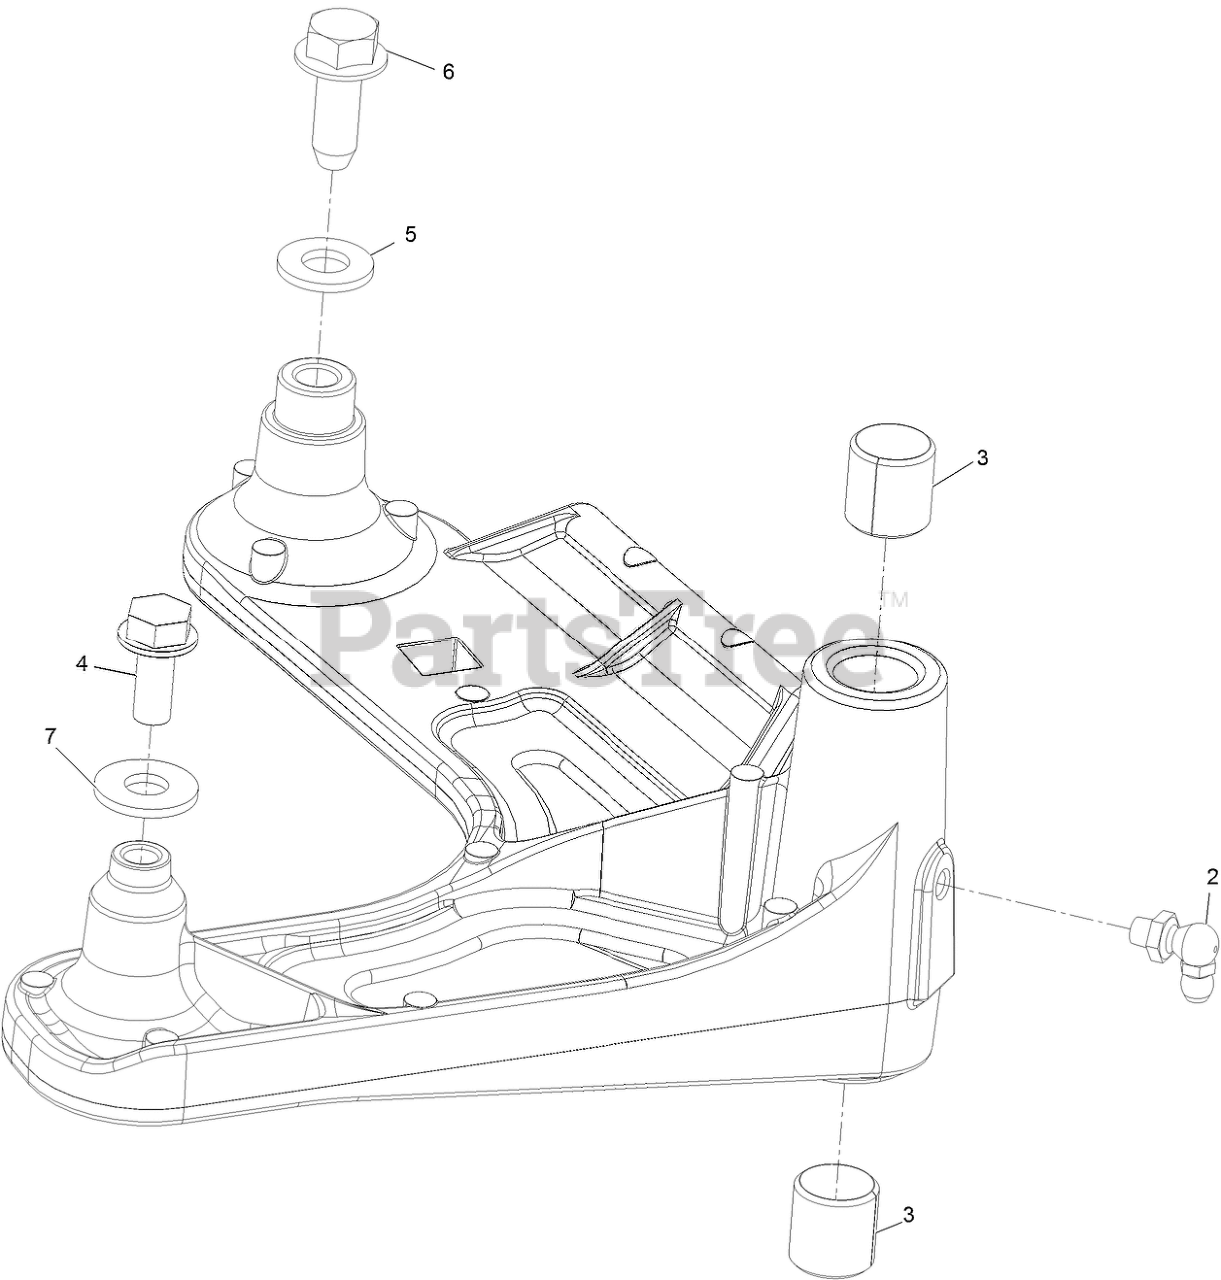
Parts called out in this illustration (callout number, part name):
2	FITTING-GREASE, 90 DEG
3	SLEEVE-BEARING
4	SCREW-THD ROLL, HWH
5	WASHER-FLAT
6	SCREW-FORMING, THREAD
7	WASHER-FLAT
